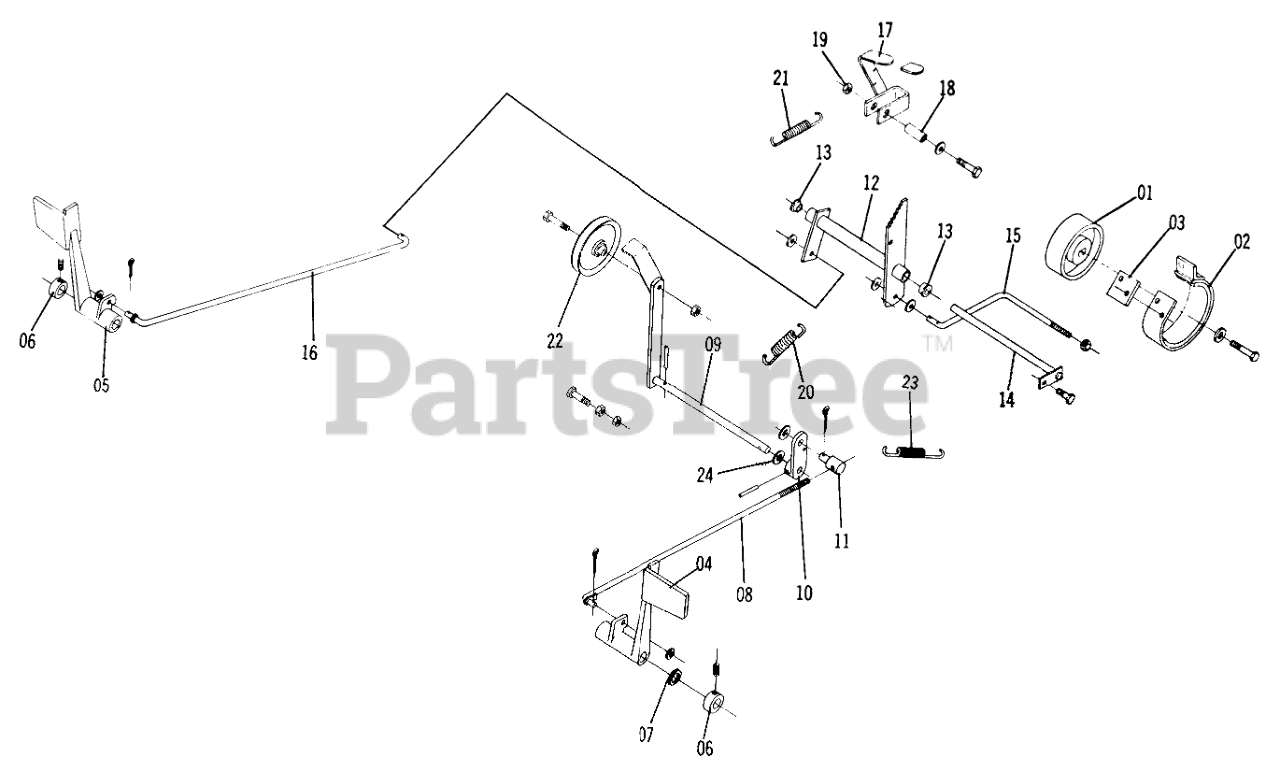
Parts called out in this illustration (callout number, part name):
6-01	Brake Drum
6-02	BRAKE BAND ASM
6-03	Plate-Stop
6-04	Clutch Pedal
6-05	PEDAL-BRAKE R
6-06	Collar
6-07	WASHER-BOWED
6-08	ROD AND GUIDE ASM
6-09	Assy.-Idler Arm
6-10	Arm Clutch Rod Pivot
6-11	Trunnion
6-12	Bellcrank Assy
6-13	BUSHING-FLANGED
6-14	Rod Assy
6-15	Brake Rod
6-16	Rod
6-17	Brake Lever Assy
6-18	SPACER
6-19	LOCKNUT-FLANGE
6-20	Spring
6-21	SPRING-EXTENSION
6-22	PULLEY-IDLER
6-23	Spring
6-24	SHIM-WASHER
